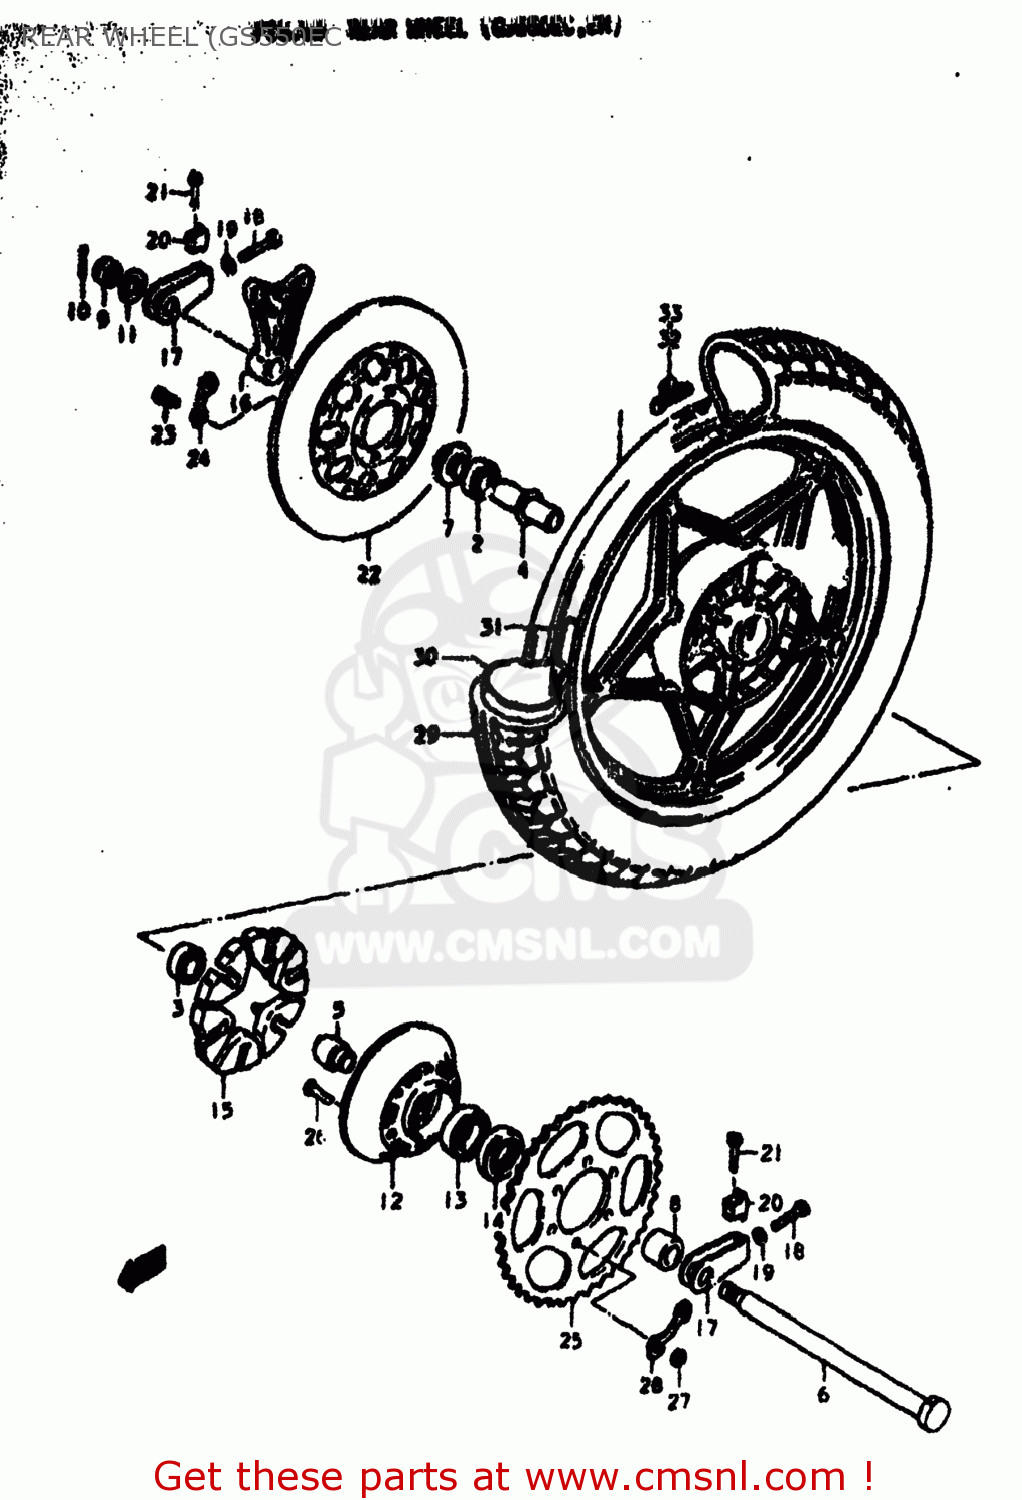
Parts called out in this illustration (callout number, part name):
1	WHEEL, REAR
2	BEARING
3	BEARING
4	SPACER,REAR HUB BEARING
5	RETAINER,REAR SPROCKET D
6	AXLE,REAR
7	SPACER,REAR AXLE
8	SPACER (17X33X21.1)
9	NUT
10	PIN,COTTER
11	WASHER (17X30X3.2)
12	DRUM,REAR SPROCKET MOUNT
13	BEARING
14	SEAL,OIL(33X62X7)
15	ABSORBER,REAR HUB SHOCK
16	BRACKET,REAR CALIPER
17	ADJUSTER,CHAIN
18	BOLT
19	NUT
20	SUPPORTER,CHAIN ADJUST
21	BOLT
22	DISC,BRAKE
23	BOLT(8X30)
24	WASHER
25	SPROCKET,RR
26	BOLT
27	NUT
28	WASHER
29	TIRE
30	TUBE ASSEMBLY,WHEEL,INNER
31	PROTECTOR,WHEEL,INNER
32	BALANCER,WHEEL
33	BALANCER,WHEEL
